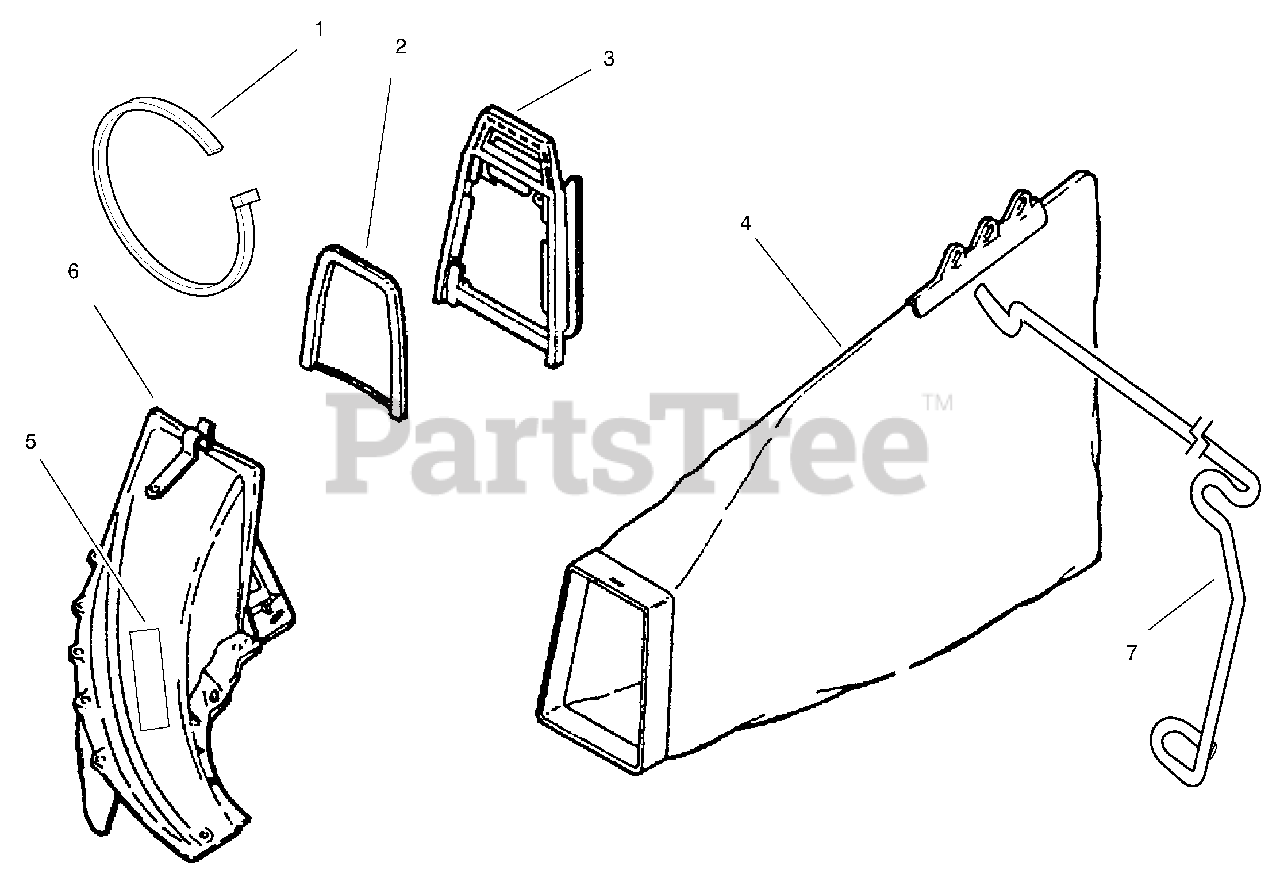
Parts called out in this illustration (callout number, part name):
1	Cable Tie
2	Chute Brace
3	Chute-Adapter
4	Side Bag
5	Decal-Danger
